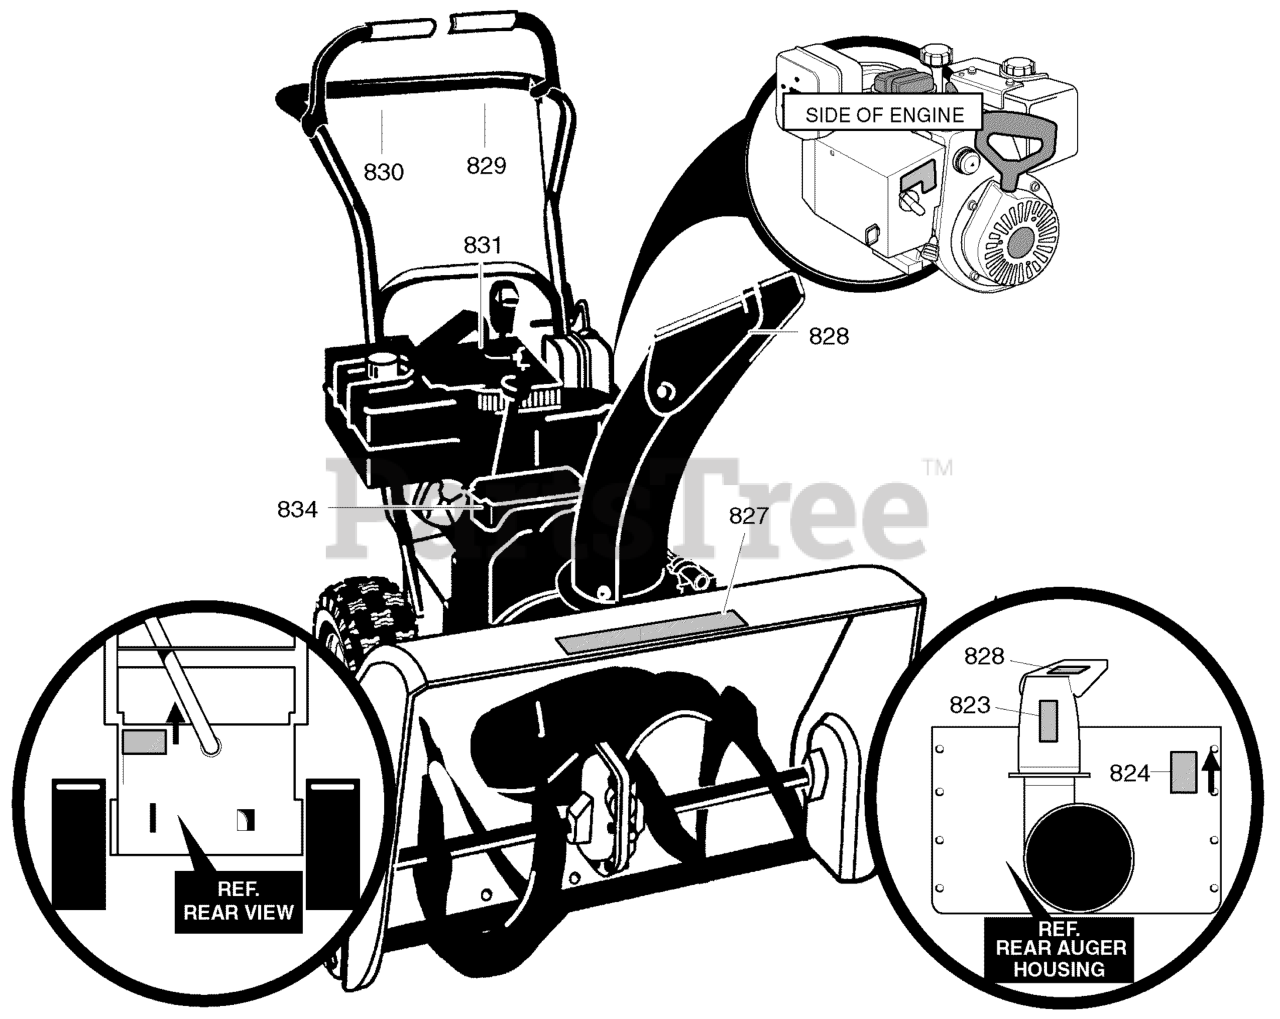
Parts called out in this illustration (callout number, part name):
823	DECAL, DANGER CHUTE HAND
824	DECAL, DANGER FOOT
827	DECAL, 9/24
828	DECAL, THROWN OBJECTS
829	DECAL, DRIVE CLUTCH
830	DECAL, AUGER CLUTCH
831	DECAL, GEAR SELECTOR
834	DECAL, TOOLBOX INFORMATION
